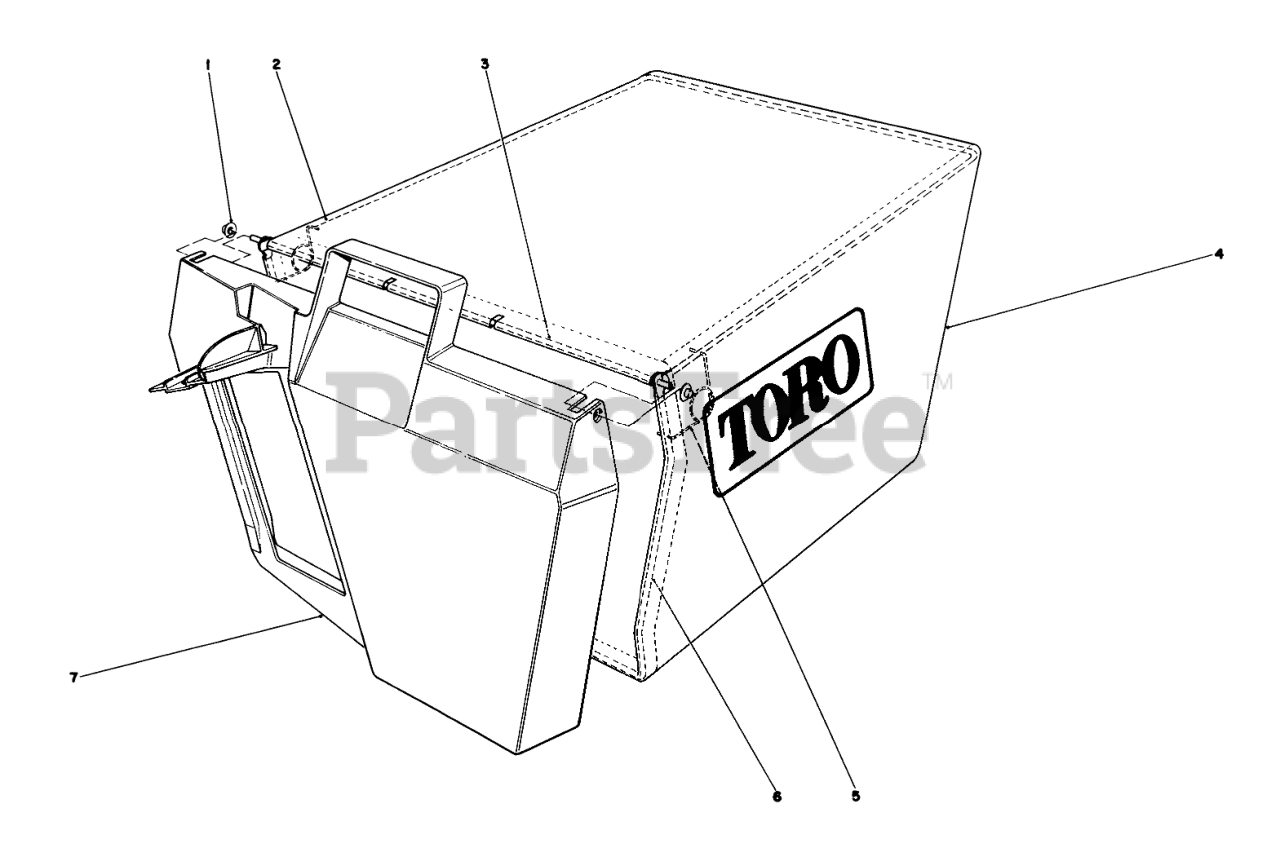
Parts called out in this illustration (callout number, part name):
1	NUT-PUSH
2	FRAME-BAG, UPPER
3	HINGE-DOOR, BAG
4	Bag
5	SPRING
6	BAG FRAME
7	Door Grass Bag
